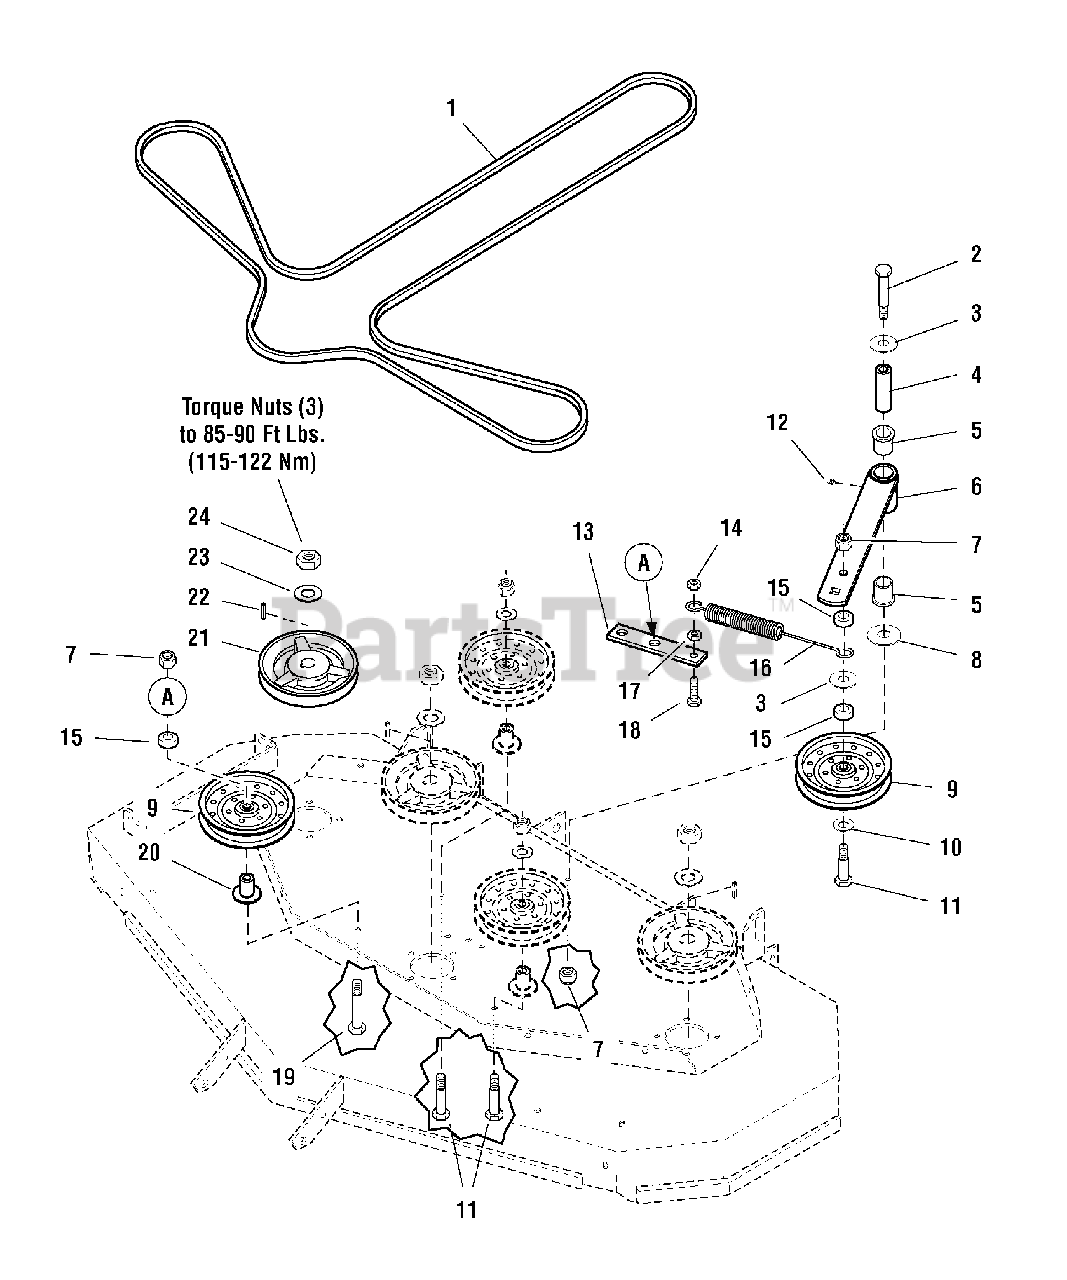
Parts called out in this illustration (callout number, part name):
1	BELT, 5V, 175.90EL, LG ARAMID, WRPD, RC
2	BOLT, 1/2-13 x 4-1/2
3	WASHER, 1/2" USS
4	SPACER, .52 x 1.00 x 3.50
5	BUSHING, Flange
7	NUT, 1/2-13 Hex Nylon Lock
8	WASHER, 5/8" SAE
9	*PULLEY, FLAT IDLER, 6-3/4"
10	WASHER, 1/2" SAE
11	BOLT, 1/2-13 x 3
12	GREASE FITTING
13	MOUNT, Idler Spring
14	NUT, 3/8-16 Hex Top Lock
15	SPACER, .52 x 1.00 x .44
16	SPRING, Extension, Swivel End
17	NUT, 3/8-16 Hex
18	BOLT, 3/8-16 x 1-1/4
19	BOLT, 1/2-13 x 3-1/2
20	WELD, MOUNT, IDLER
21	SPINDLE PULLEY
22	KEY, 1/4 SQ. X 1-1/4
23	WASHER, 3/4" Belleville
24	NUT, 3/4-16 Hex
